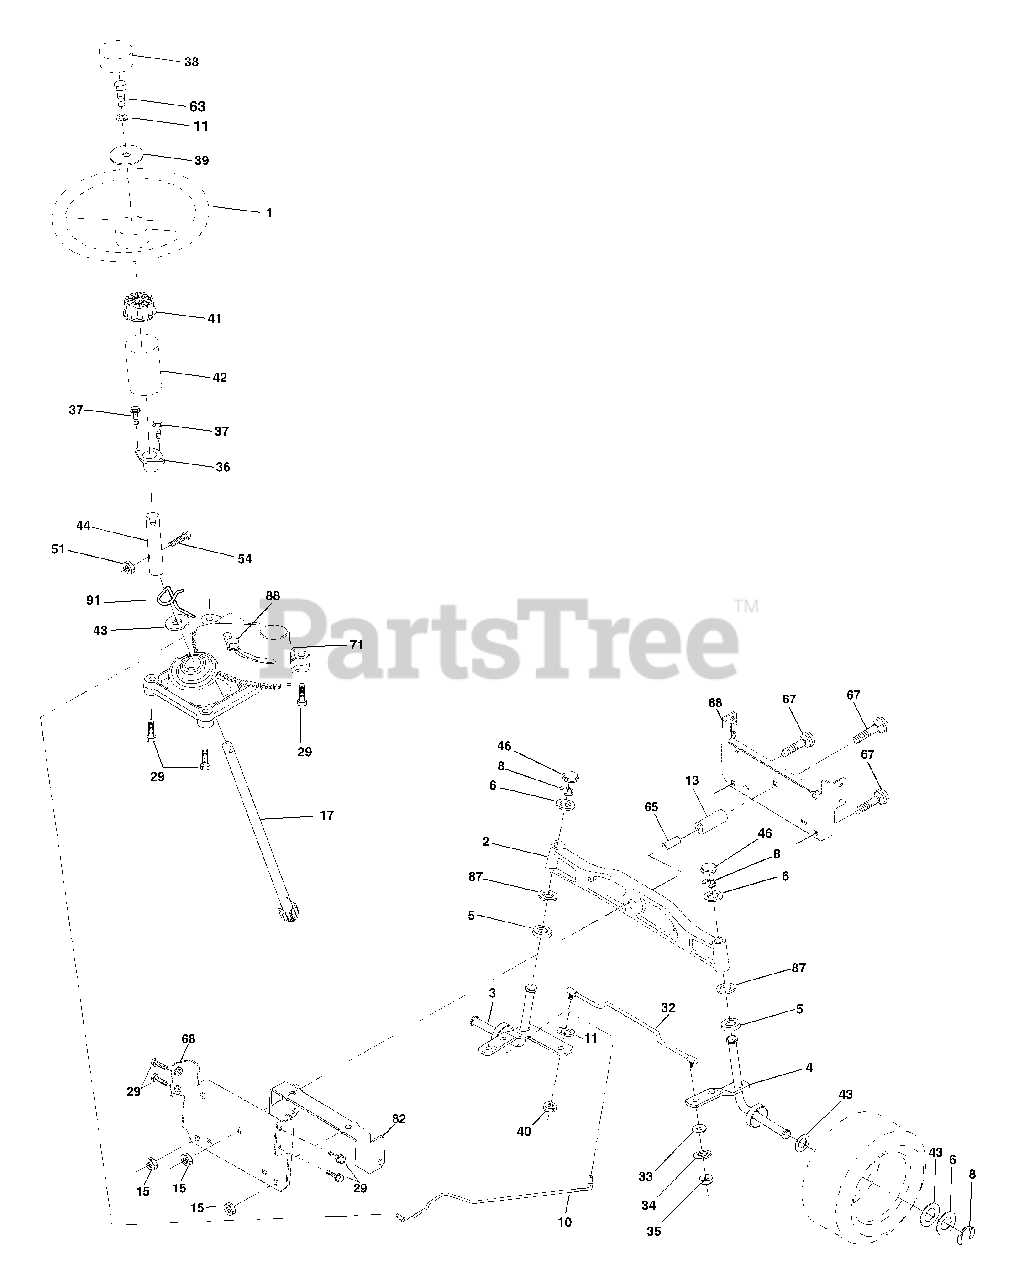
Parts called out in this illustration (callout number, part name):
1	Wheel Steering
2	Axle Cast LT Machined
3	Spindle Asm Cast LH
4	Spindle Asm Cast RH
5	Bearing Race Thrust Harden
6	Washer 25/32 X 1-5/8 X 16 Ga
8	Ring Klip #t5304-75
11	Washer Lock Hvy Hlcl Spr 3/8
13	Spacer Brg Axle Front
15	Nut Hex Flange Lock Yel D
17	Shaft Asm Steering
29	Screw 3/8-16x3/4
33	Washer 11/32 x 3/4 x 16 Ga.
34	Washer Lock Hvy. Helical 5/16 SD
35	Nut Crown Lock 5/16-24
36	Bushing Strg
37	Screw TT #32.5 x 5 x 3/8 Flange
38	Cap Wheel Steer
39	Washer 13/32 x 2 3/8 x 12 Ga.
40	Nut Lock Center 3/8-24 Unf
41	Adaptor Wheel Strg
42	Boot Dash Steering
43	Washer 25/32 X 1 1/4 X 16 Ga
44	Extension Steering Non-adjust
46	Cap Spindle Fr Top Blk
51	Nut Lock Hex W/Ins 5/16-18 UNC
54	Bolt Fin Hex 5/16-18 UNC x 1-1/4
63	Bolt Fin Hex 3/8-16 UNC x 1 Gr. 5
65	Spacer, Brace Axle
67	Bolt Rdhd 3/8-16 x 2-1/4
68	Brace, Axle
71	Steering Asm.
82	Bracket Susp Chassis Front 15"
87	Washer Flat .781 x 1-1/2 x .14
88	Bolt Shoulder 7/16-20
91	Clip, Steering
